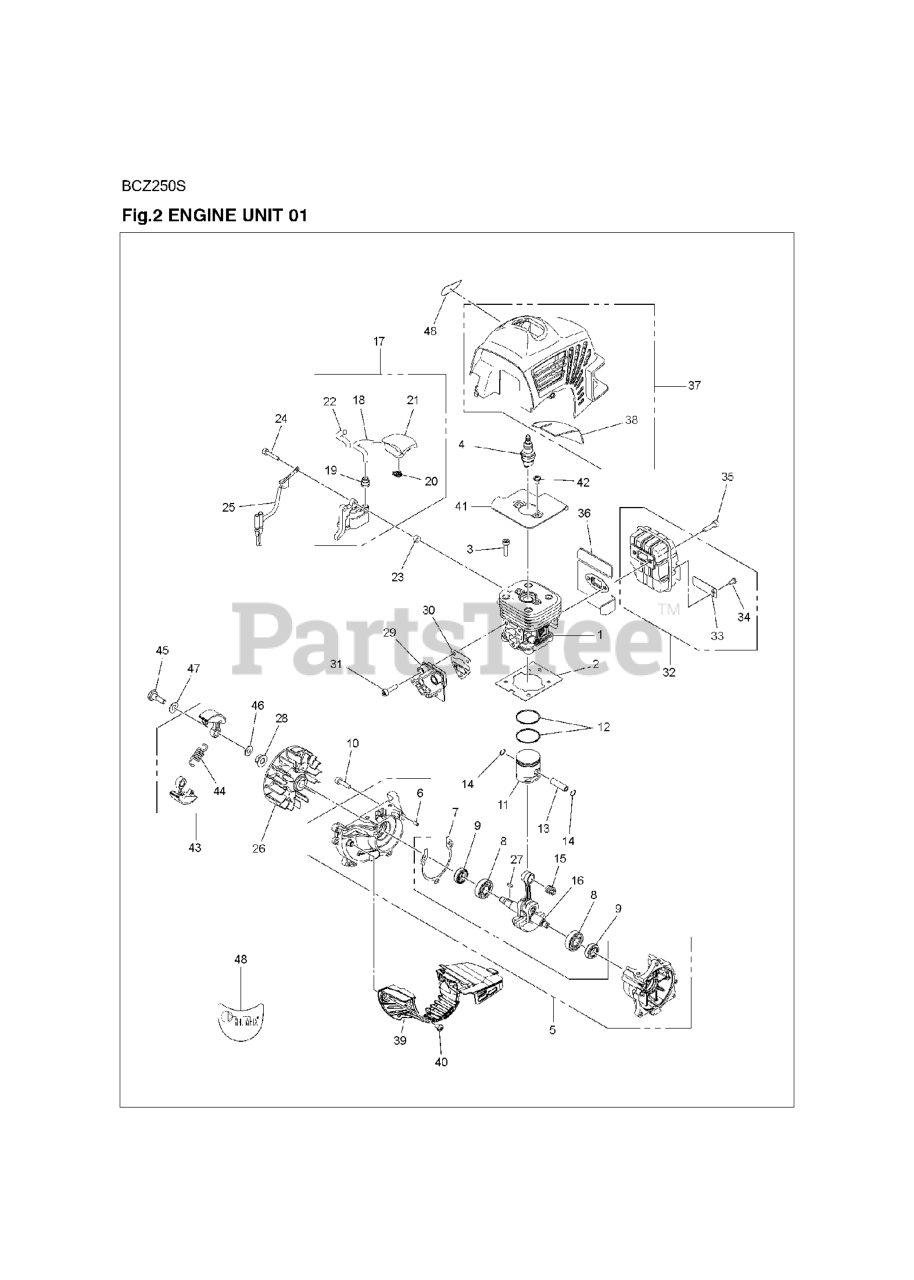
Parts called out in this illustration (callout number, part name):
1	CYLINDER COMP
2	GASKET BASE
4	SPARK PLUG, BPMR8Y
5	CRANKCASE ASSY
7	GASKET CASE
12	RING, PISTON
13	PIN
16	CRANKSHAFT COMP
17	IGNITION MODULE
18	IGNITION CABLE
19	HUB CAP 848F6L71E0
21	SPARK PLUG CAP
22	TUBE (RPLS 263072210)
24	BOLT M4 X 25
25	SHORT CIRCUIT CABLE
26	FLYWHEEL
27	KEY
28	NUT
29	INSULATOR
32	MUFFLER ASSY
33	SPARK ARRESTER
34	SCREW CRPANT TYPE F ST4.2X9.5
36	GASKET MUFFLER
37	CYLINDER COVER COMP
38	SHEET HEAT INSULATION
39	GUARD,COOLING AIR INTAKE
41	PLATE CYLINDER
43	CLUTCH ASSY
44	CLUTCH SPRING
48	DECAL BRAND
